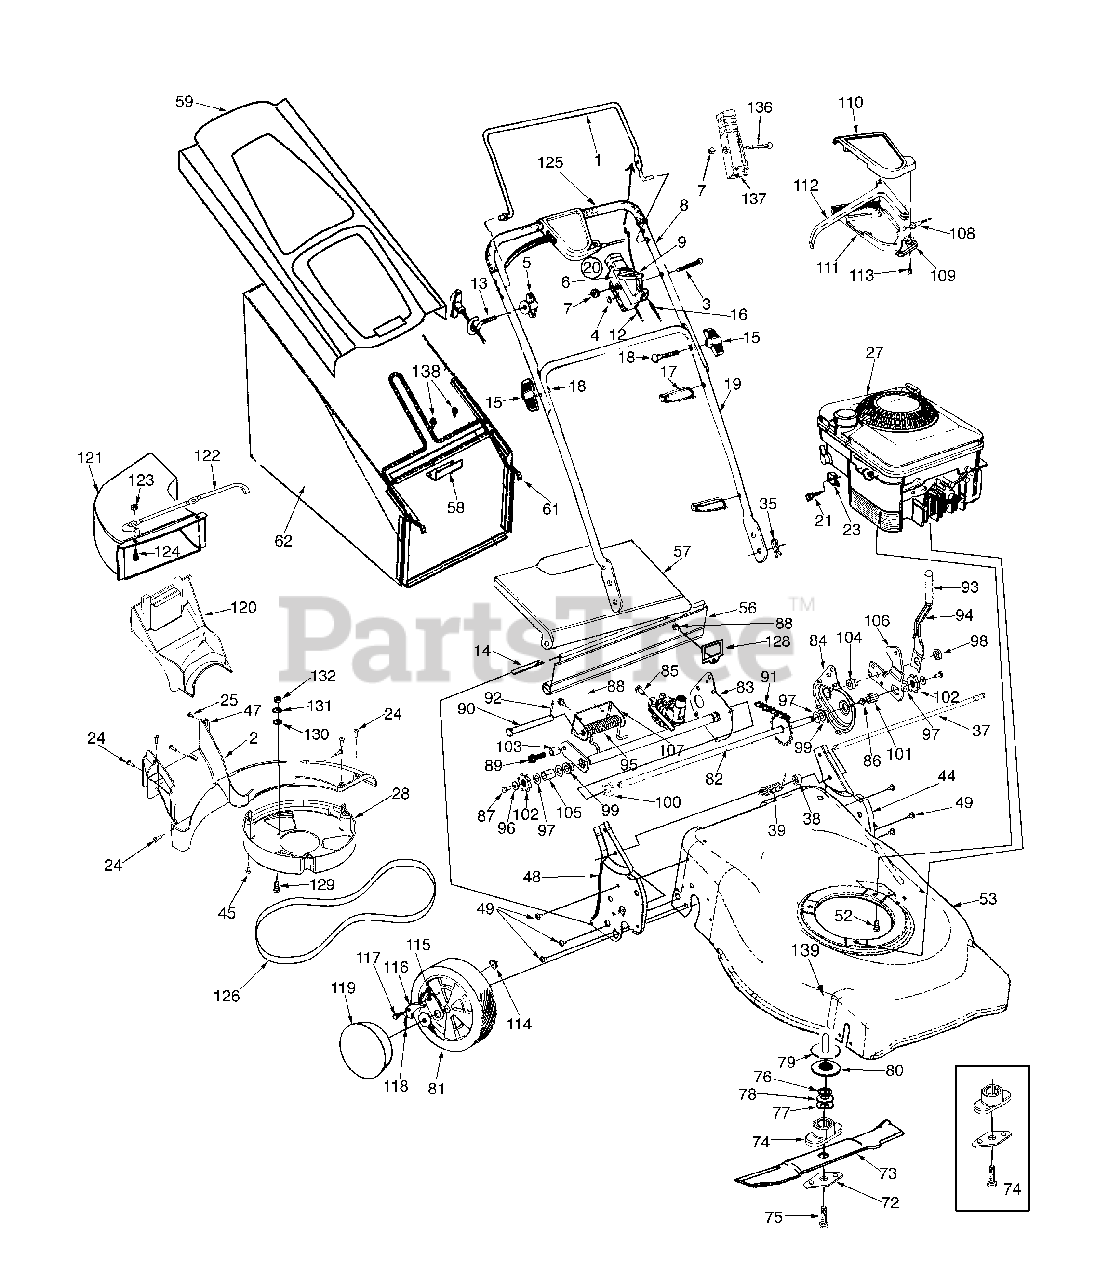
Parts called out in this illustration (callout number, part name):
2	Baffle
3	Oval C-Sunk Mach - Screw
4	Spring Washer .66" ID
5	Handle Knob 1/4-20 Thd.
6	Throttle Body
7	Hex L-Nut 1/4-20
9	Throttle Lever
12	Throttle Control Wire - 47"
13	Rope Guide
14	Wire-47" Lg.
15	Hand Knob
16	Control Cable-55"
17	Cable Tie
18	Cr.Hd. Bolt 5 / 16-18 x 2" Lg.
20	Throttle Ass'y Comp
21	Hex Self-Tap Scr. #10-32 x .62"
23	Cable Clamp (B&S)
24	Screw H.L. 12-24
25	Screw Mach. B Tapp.
27	Engine
28	Belt Cover
35	Int. Cotter Pin 5/15" Dia.
37	Pivot Rod
38	Spacer.385 I.D.
39	Torsion Spring L.H.
47	U-Nut
52	Hex L-Wash. Hd. Scr. 3/8-16 x 1"
53	21" Deck Ass'y w/ MTD Icon
56	Rear Flap 17.77 Lg.
62	Grass Bag - Black
72	Blade Bell Support
73	21" Mulching Blade w/Star
74	Blade Adaptor Kit w/Star
75	Hex Bolt 3/8-24 x 2.5 Lg.
76	Spacer
77	Fl. Wash. .885 x 1.85 x .06
78	Spr. Wash. .890 x .7 x .04
79	Pulley Half - Upper
80	Pulley Half - Lower
81	Wheel Assembly
82	Axle Assy: RR
86	Scr. TT 1/4-20
87	Hx Cap Screw 1/4-20
88	Hex Washer Screw 1/4-20 x .625
89	Scr 3/8 - 16 x 1.25
90	Pin - Clv. .500 Dia. x .4.62 Lg.
91	Chain:Endless 48:.500P x 22 Lg.
92	Pin-Cotter .125 O.D. x .75
93	Grip-Foam
94	Spring Lever
95	Torsion Spring
96	Bell Washer.265 x .75 x .062
97	Wash.Flat.508 I.D. x 1.0 O.D.:.020
98	Nut - Shoulder.625 x .165 Lg.
99	Bearing-Fig Hex
100	Bearing-Fig. Hex
101	Bearing-Sleeve
102	Ratchet Wheel
103	Spacer - .385 x .625 x .700
104	Spacer-Shld 385 I.D.x.715 Lg.
105	Spacer Slv. .520 I.D. x .950 Lg.
109	Mounting Cap
110	Control Cover - Upper
111	Control Cover - Lower
112	Lever
113	Screw #10-1 s x .625
114	Weld Top L. 1/4-20
115	Pawl Plate
117	Shldr. Scr. .340 x .285
118	Spring, Ratchet
119	Hub Cap
120	Mulch Plug
121	Chute Deflector
122	Chute Mounting Rod
123	Hex-L-Nut 1/4-20 thd.
124	Mach. Scr. 1/4-20
125	Foam Grip
126	Belt
130	Lockwasher 1/4" Reg,
131	Fl. Wash. .271 x .630 x .065
132	Nut 1/4-20
136	Scr. 1/4-20:1.31 Lg.
137	Housing (w/o Throttle)
138	Hex Washer Screw 1/4-20 x .625
139	Spacer
